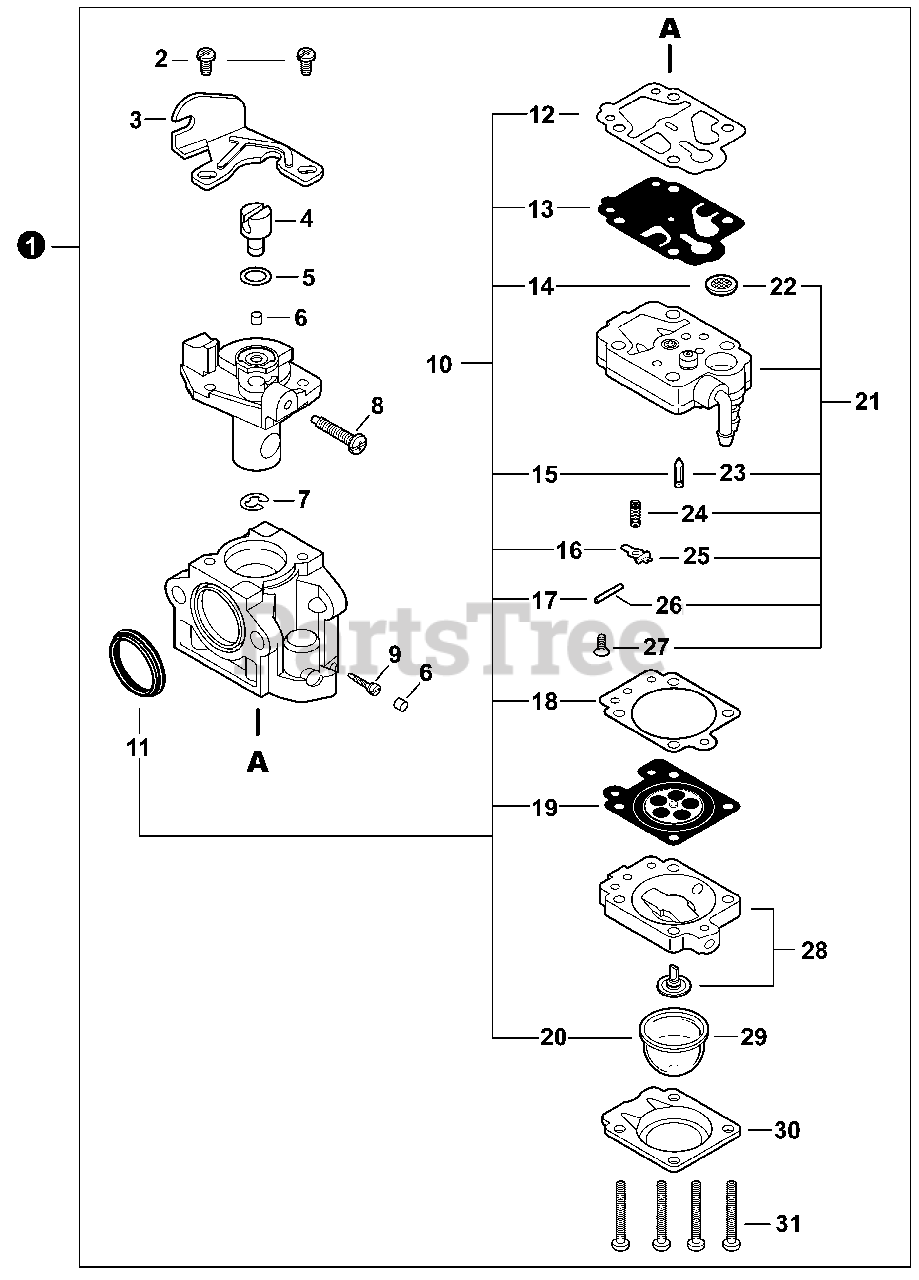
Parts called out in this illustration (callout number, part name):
1	CARBURETOR - WYK-233A
3	BRACKET, THROTTLE CABLE
9	NEEDLE, HIGH SPEED
10	REPAIR KIT, CARBURETOR
11	RING, PACKING
12	GASKET, PUMP
13	DIAPHRAGM, PUMP
14	SCREEN, FUEL INLET
15	VALVE, INLET NEEDLE
16	LEVER, METERING
17	PIN, METERING LEVER
18	GASKET, METERING DIAPHRAGM
19	DIAPHRAGM, METERING
20	BULB, PURGE
21	BODY ASSY, PUMP
22	SCREEN, FUEL INLET
23	VALVE, INLET NEEDLE
24	SPRING, METERING LEVER
25	LEVER, METERING
26	PIN, METERING LEVER
27	SCREW
28	BODY ASSY, PURGE
29	BULB, PURGE
30	RETAINER, PURGE BULB
